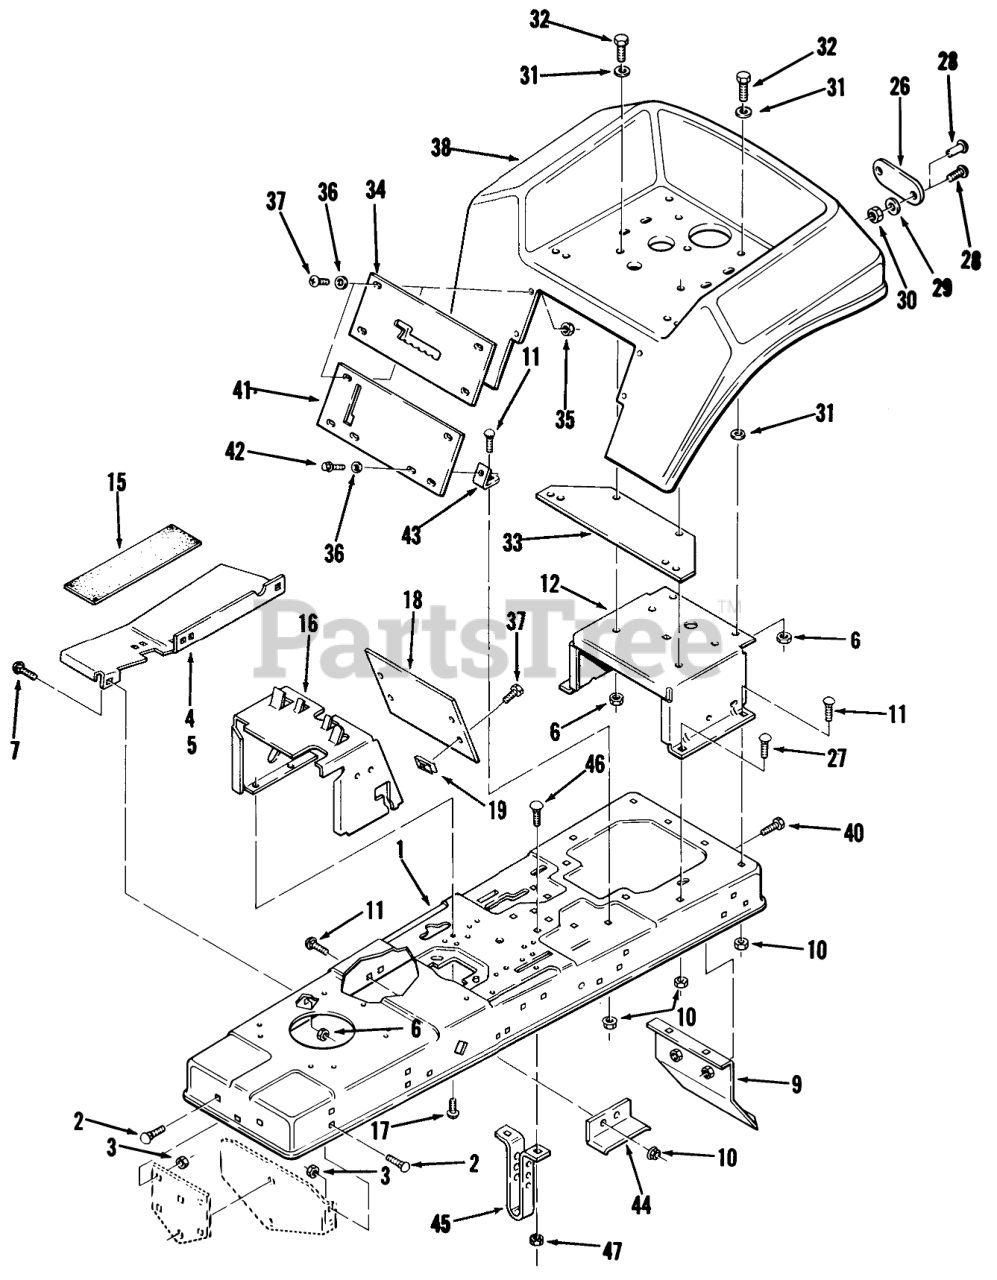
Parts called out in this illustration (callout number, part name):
1	Frame
2	CARRIAGE BOLT -4
3	Nut
4	Footrest RH
5	Footrest LH
6	Nut
7	CARRIAGE BOLT -4
9	Hitch-Drawar
9	Hitch Drawbar
10	Nut
11	CARRIAGE BOLT -4
11	Carriage Bolt 1/4-20 x 1
12	ASSY SEAT SUPPORT R
12	SUPPORT-SEAT R
15	PAD-FOOTREST
16	Hoodstand
17	SCREW
18	PLATE-HOODSTAND REAR
26	Reflector
27	Bolt
28	Screw
28	Poprivet
29	Lockwasher
30	Nut
31	WASHER
32	Bolt
33	PLATE-SEAT R
33	Seat Plate
34	Shift Plate
35	Nut
37	Screw
38	Fender
40	Bolt
41	Front Fender Plate
42	Bolt
43	BRACKET-FENDER
44	Belt Support
45	GUIDE-MOWER
46	Bolt-Carriage
47	Nut
